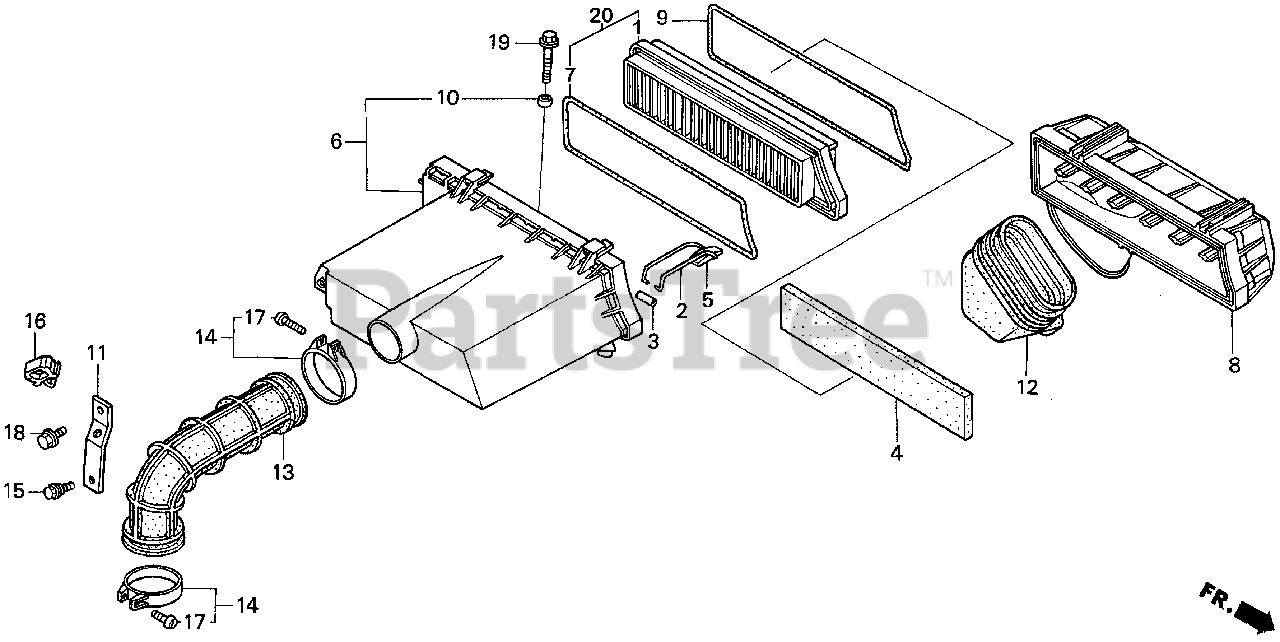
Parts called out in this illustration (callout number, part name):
1	ELEMENT SET, AIR CLEANER
1	ELEMENT, AIR CLEANER
2	CLIP, WIRE
3	COLLAR, CLIP BRACKET
4	FILTER (OUTER)
6	HOUSING, AIR CLEANER
7	GASKET, ELEMENT
8	COVER, AIR CLEANER
9	GASKET, AIR CLEANER COVER
10	COLLAR B, AIR CLEANER
11	STAY, AIR CLEANER
12	TUBE, AIR IN.
13	TUBE, AIR CLEANER CONNECTING
14	BAND, AIR CLEANER CONNECTING TUBE
15	BOLT, FLANGE (6MM)
16	CLIP, WIRE HARNESS
17	SCREW, PAN (4X20)
18	BOLT, FLANGE (6X12)
19	BOLT, FLANGE (6X30)
